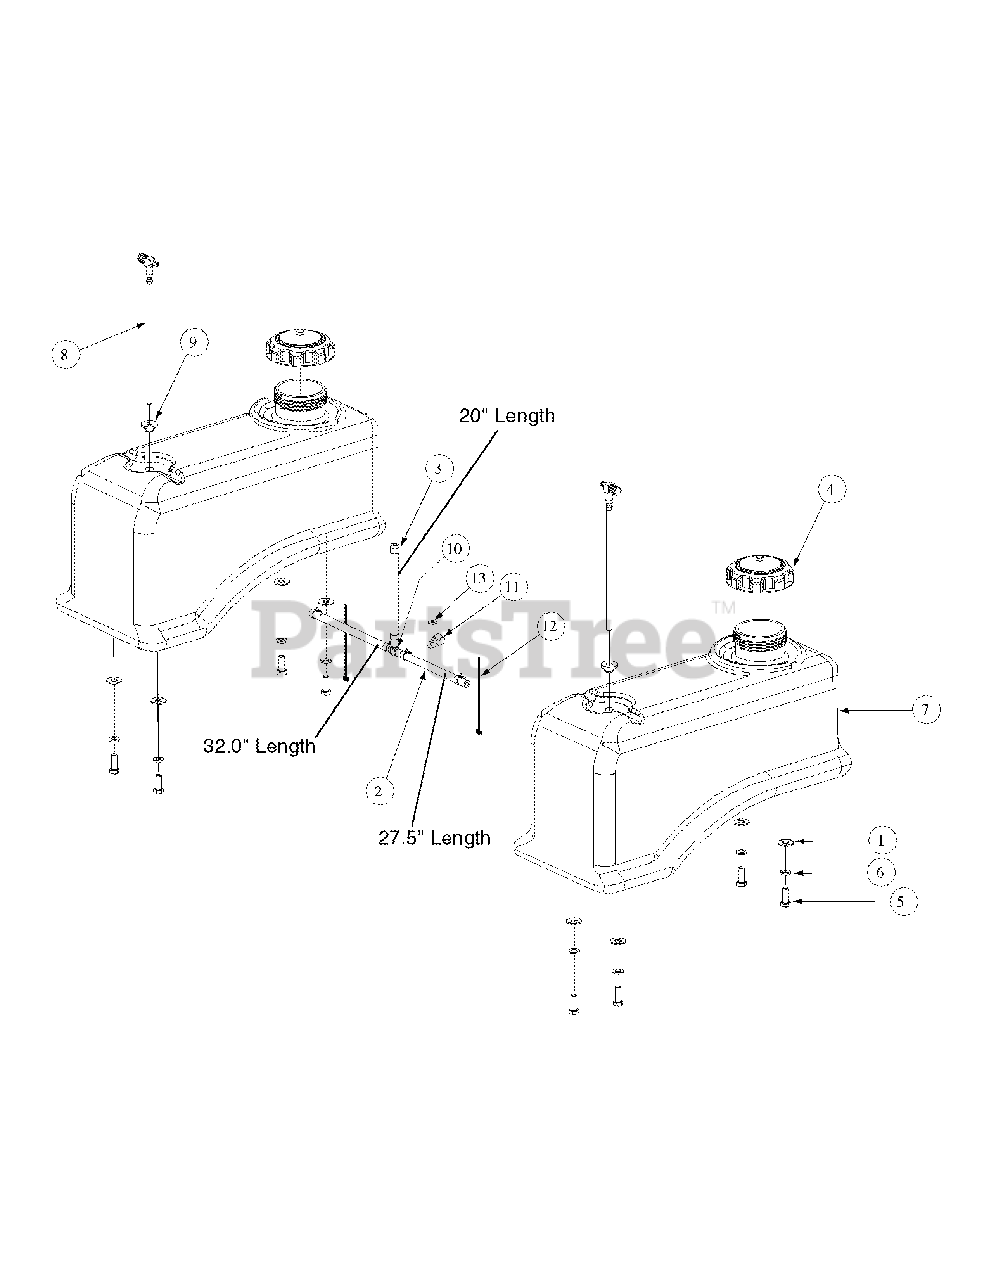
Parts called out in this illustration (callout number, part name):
1	Flat Washer, .406 ID, 1.0 OD, .105
2	Hose, 1/4" Fuel Line 79.5"
3	Clamp, Union
4	Fuel Cap, 3.5
5	Hex, Cap Screw, 3/8-16, .88
6	Lock Washer, 3/8
7	Fuel Tank
8	Fuel Fitting
9	Fuel Tank Grommet
10	Tee Fitting, Fuel
12	Cable Tie
13	Flatwasher 1/4 x .630 x .0515
